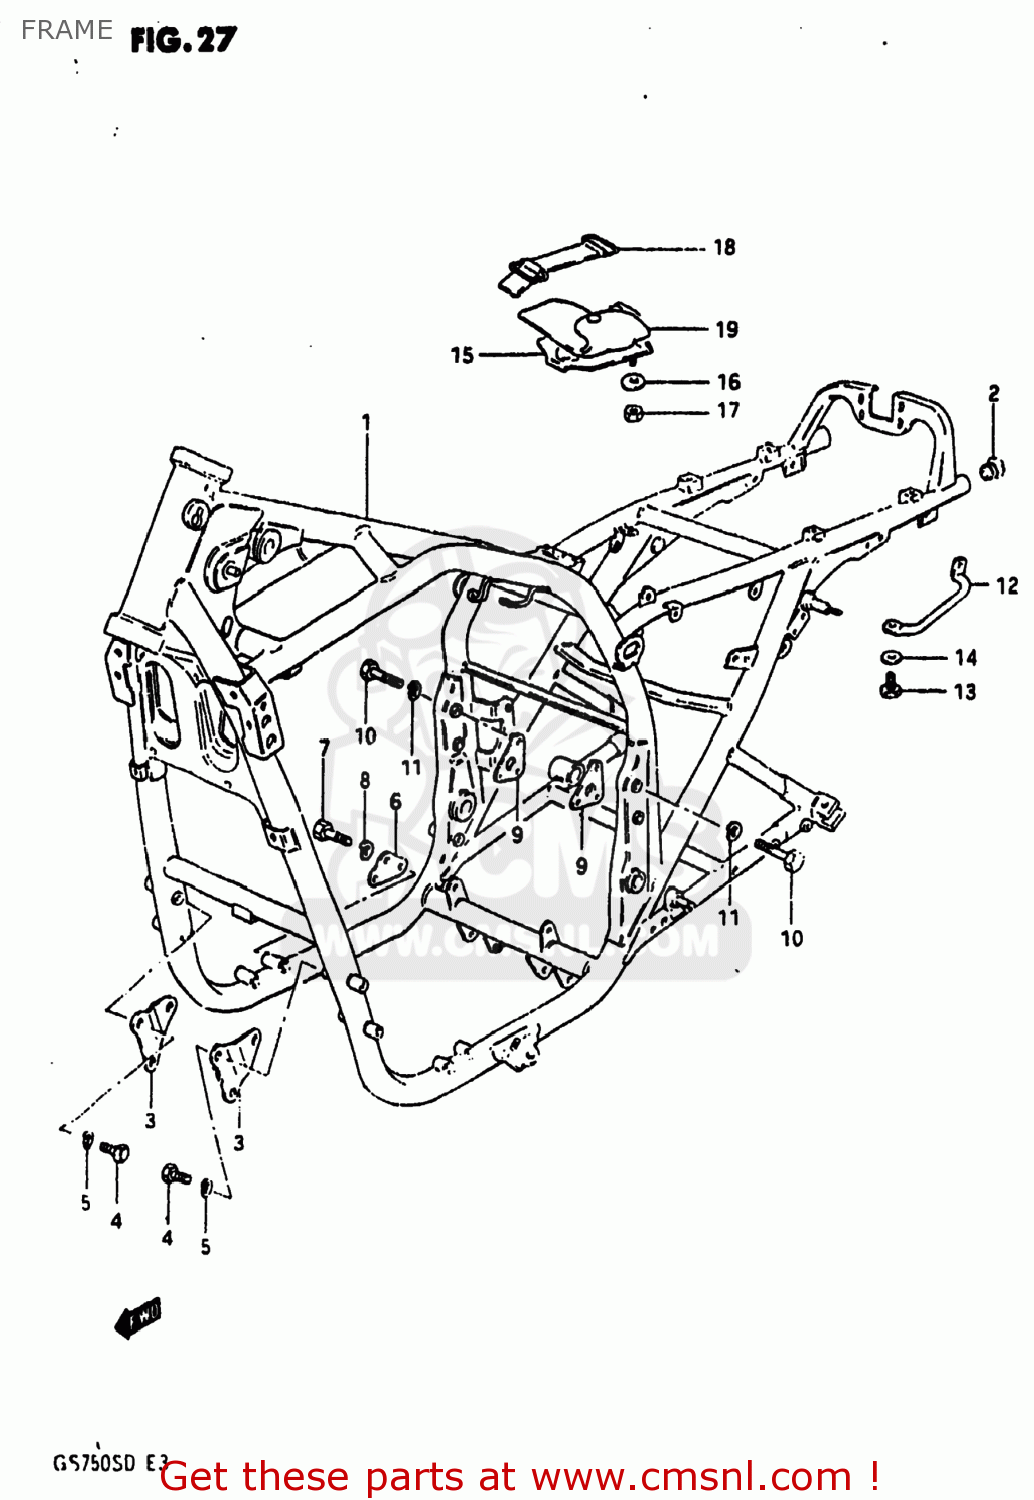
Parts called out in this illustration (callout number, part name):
1	FRAME
2	CAP(OD:26)
3	PLATE,ENG MTG NO.1
4	BOLT(8X65)
5	LOCK WASHER
6	PLATE,ENG MTG NO.2
7	BOLT 8X16
8	LOCK WASHER
9	PLATE,ENG MTG NO.4
10	BOLT, FRONT FENDEER FRONT
11	LOCK WASHER
12	GRIP,STAND
13	BOLT
14	WASHER
15	HOLDER,TOOL
16	WASHER(6.5X30X1.6)
17	NUT
18	BAND
19	TOOL SET
